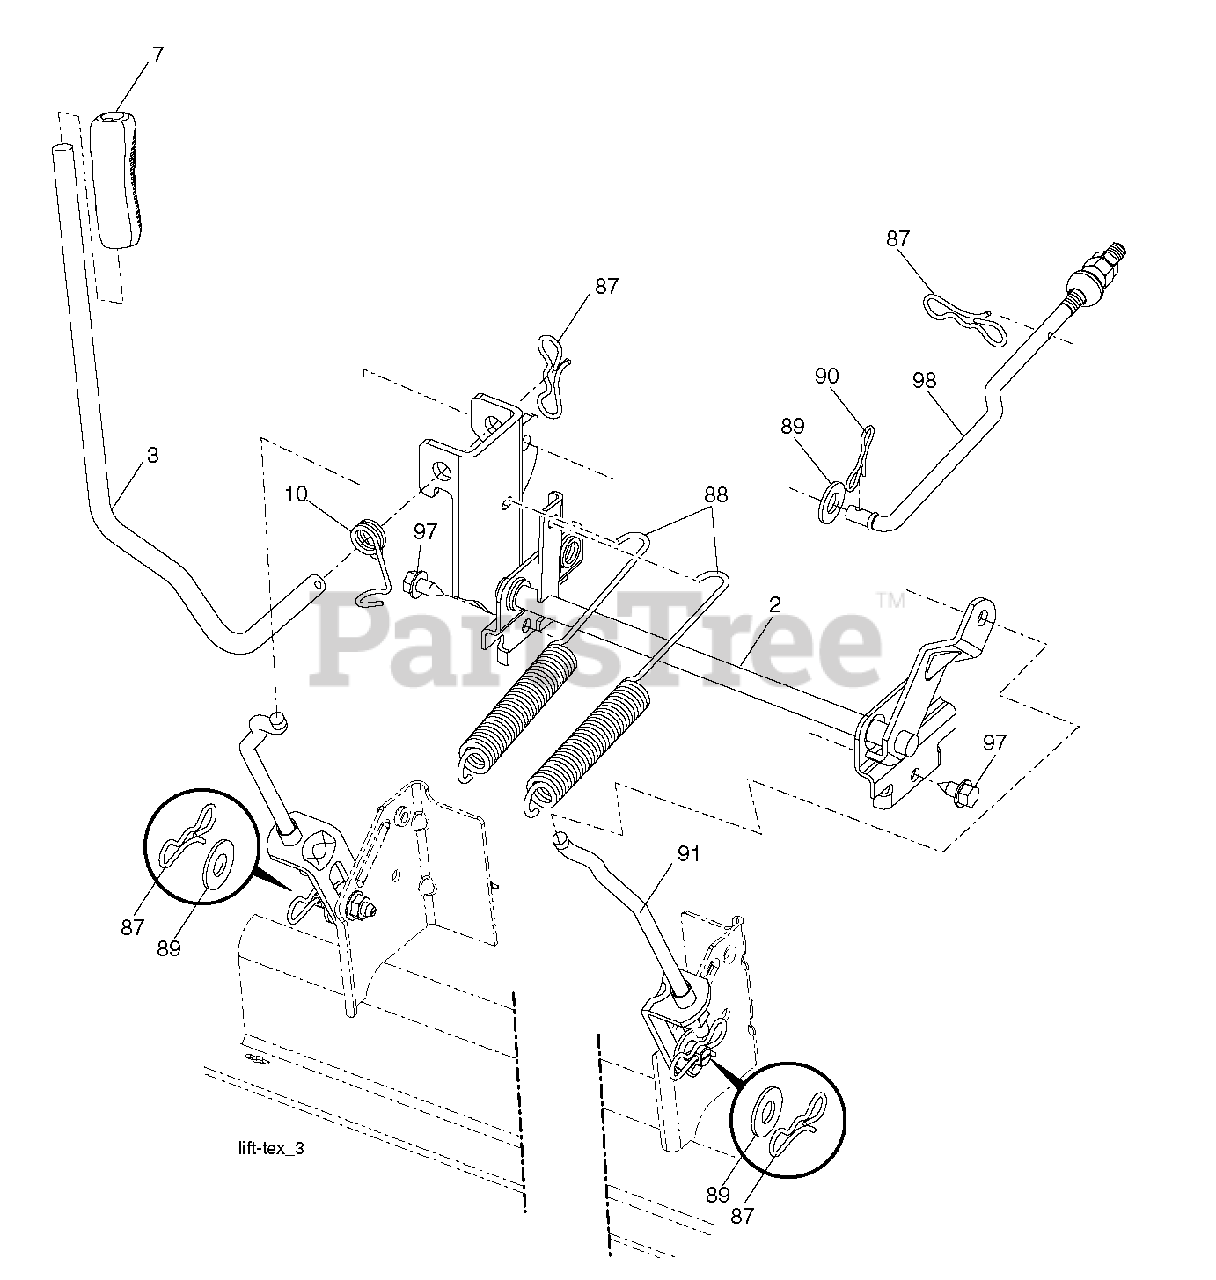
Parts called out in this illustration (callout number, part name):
2	SHAFT.ASM.CROSS.LIFT
3	LEVER.LIFT.HANDLE.GT
7	GRIP.HANDLE.LIFT.PVC.BLACK
10	SPRING.TORSION.LIFT.HANDLE
87	PIN.COTTER.7/16.BOW TI.
88	SPRING.LIFT.ASSIST.GT2
89	WASHER.CLEAR.ZINC
90	PIN.COTTER.5/16.BOW TI
91	LINK.ASM.LIFT.54"TG
97	SCREW, 3/8-16X3/4
98	LINK.ASM.SUSP.FRONT.MWR.10.5
